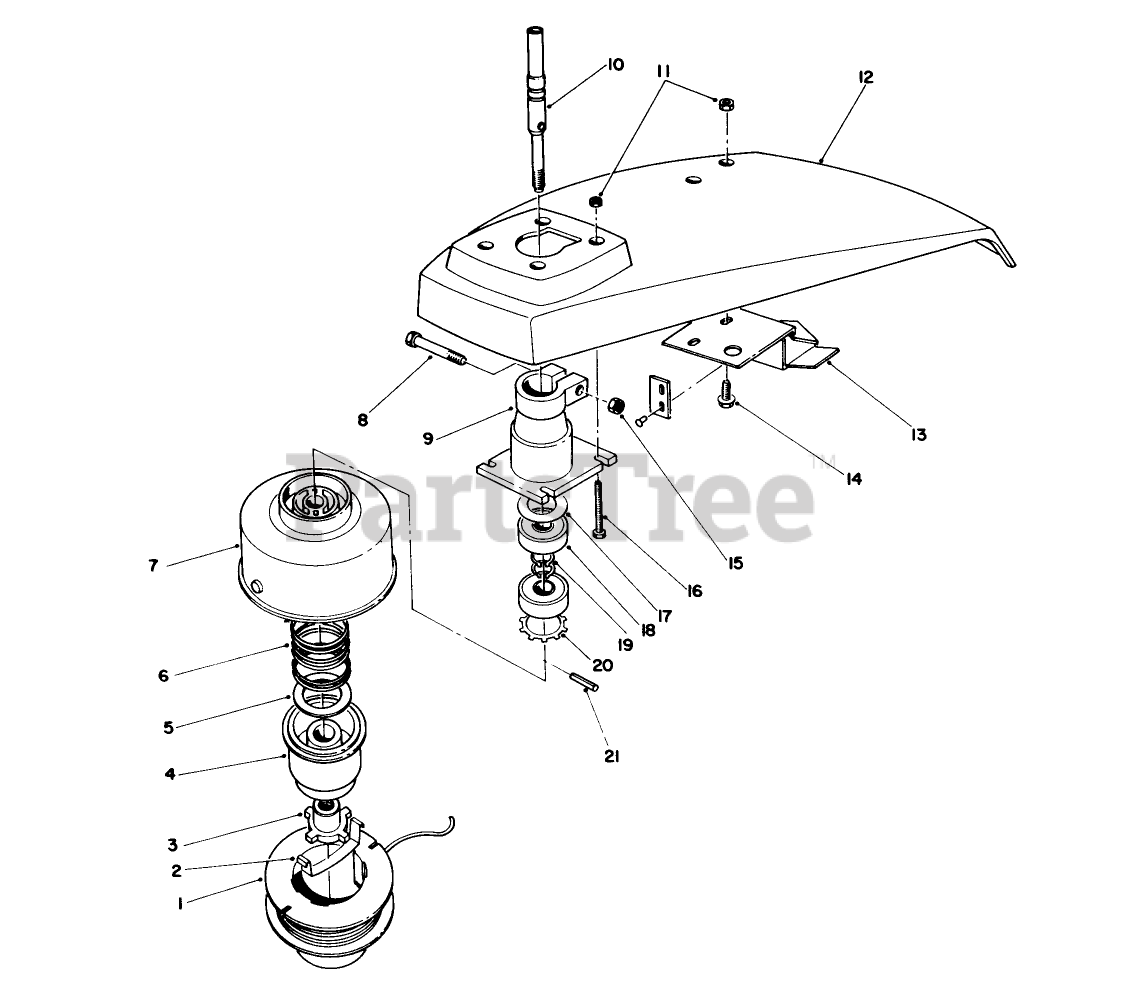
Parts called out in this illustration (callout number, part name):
1	Spool-Prewound .08 Dia. 38- (Incl. Ref. #2)
2	SADDLE-SPOOL CAP
3	DRIVER
4	SPOOL CORE
5	WASHER-FLAT
6	SPRING COMPRESSION
7	DRUM/EYELET
8	SCREW-HH
9	Housing-Bearing (Incl. Ref. #10, 17-21)
10	Shaft-Power
11	NUT-LOCK, NI
12	GRASS SHIELD-PLASTIC
13	BRKT/KNIFE BLD ASM
14	SCREW-HWH
15	NUT-LOCK, NI
16	SCREW-HH
17	FLAT WASHER
18	BEARING-BALL
19	RING-SNAP
20	SPRING GRIP
21	COIL PIN
